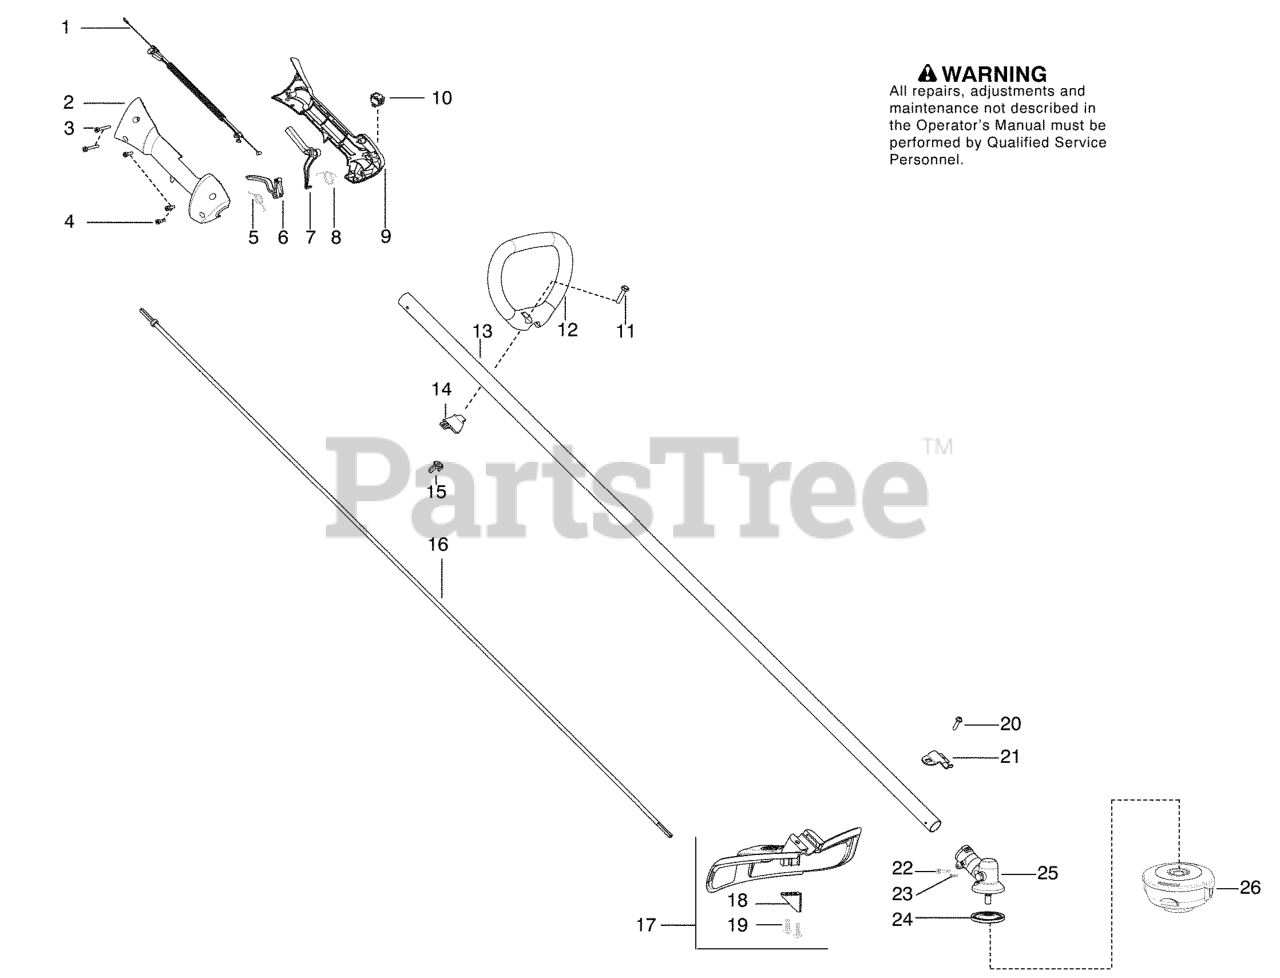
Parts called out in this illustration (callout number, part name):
1	ASSY-CABLE WIRE HARNESS
2	HOUSING-THROTTLE RH
4	SCREW M4 X 1.75 PT 16MM
5	SPRING TRIGGER
6	TRIGGER THROTTLE
7	THROTTLE LOCKOUT
8	SPRING LOCKOUT
9	HSG THROTTLE LH
10	KIT SWITCH
11	BOLT, TYPE 2
13	KIT DRIVESHAFT SST
14	CLAMP ASSIST HANDLE
15	WINGNUT, TYPE 2
16	FLEXSHAFT 57"
17	KIT COBI SHIELD
18	Limiter-Line
20	SCREW 1/4-20 X 7/8 (TAP
21	BRACKET SHIELD STRAIGHT SHAFT
22	SCREW - CARB. ADAPTOR
24	DRIVE DISC
25	ASSY GEARBOX
26	T25 TRIM HEAD 10MM LH
